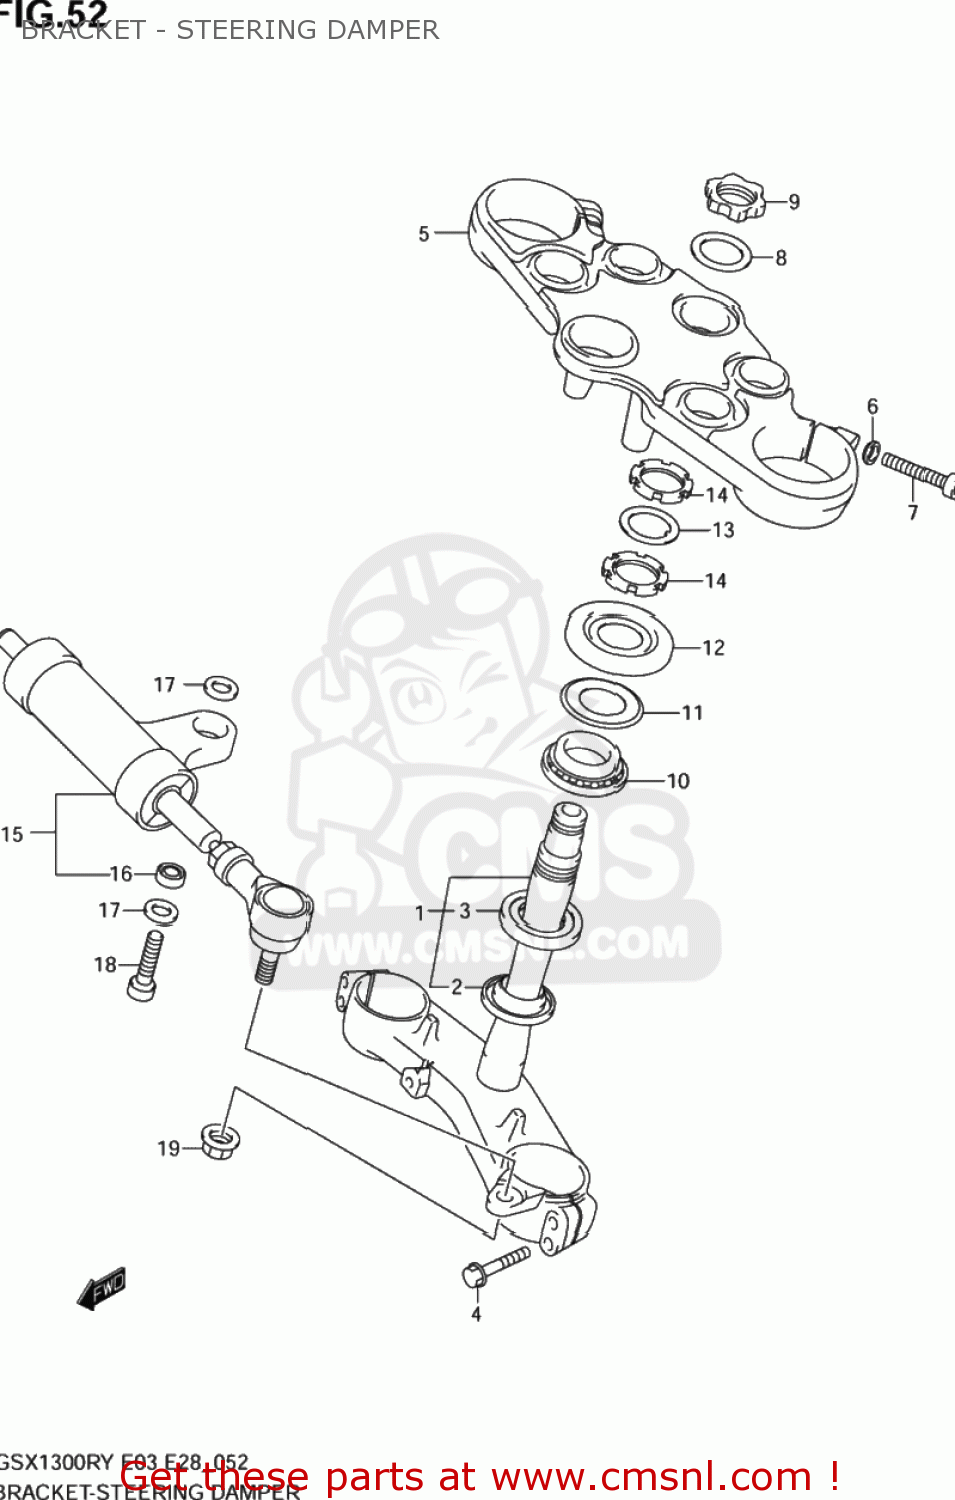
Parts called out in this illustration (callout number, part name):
1	BRACKET,FR FORK UNDER
2	SEAL,STEERING LWR
3	BEARING(30X55X17)
4	BOLT
5	BRACKET,FR FORK UPR
6	WASHER
7	BOLT
8	WASHER,STEM HEAD(24.5X34X1.6)
9	NUT
10	BEARING(30X55X17)
11	SEAL,STEERING LWR
12	COVER,STEERING UPR
13	WASHER,STEERING STEM
14	NUT,STEERING STEM
15	DAMPER ASSY,STEERING
16	BEARING(8X17.5X11)
17	SEAL,PILLOW BALL,DUST
18	BOLT
19	NUT
